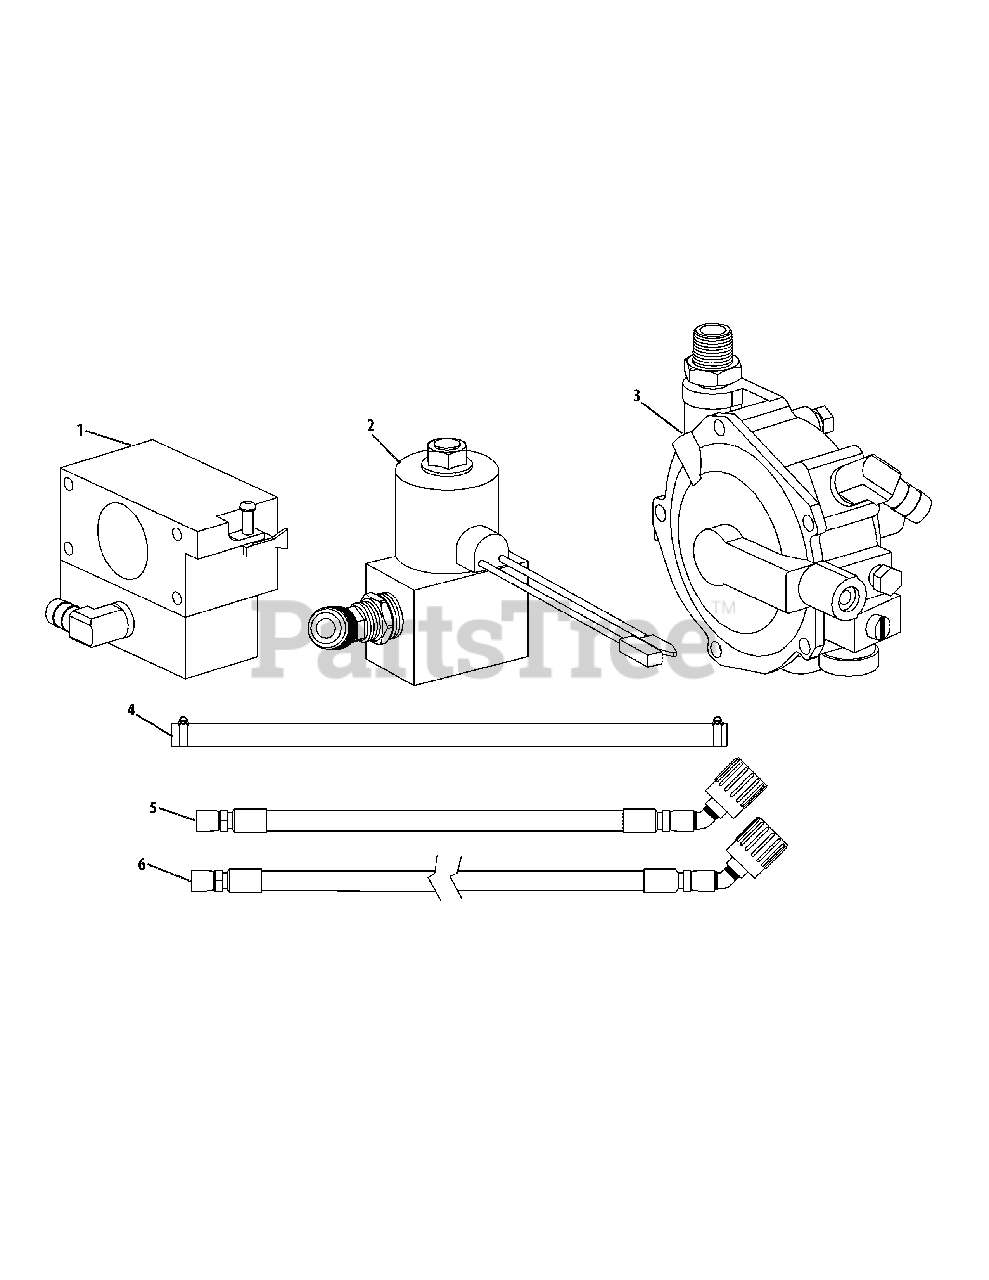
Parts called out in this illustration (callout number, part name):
1	Carburetor Kit (FX850-AS00-S)
1	Carburetor Kit (FXT00V-BS04-R)
2	Lockoff Engine Kit
3	Regulator Engine Kit
4	Hose Kit, 1/2 x 21 (FX850-AS00-S)
4	Hose Kit, 5/8 x 18.5 (FXT00V-BS04-R)
5	Regulator Hose Kit, 19"
6	Regulator Hose Kit, 51"
